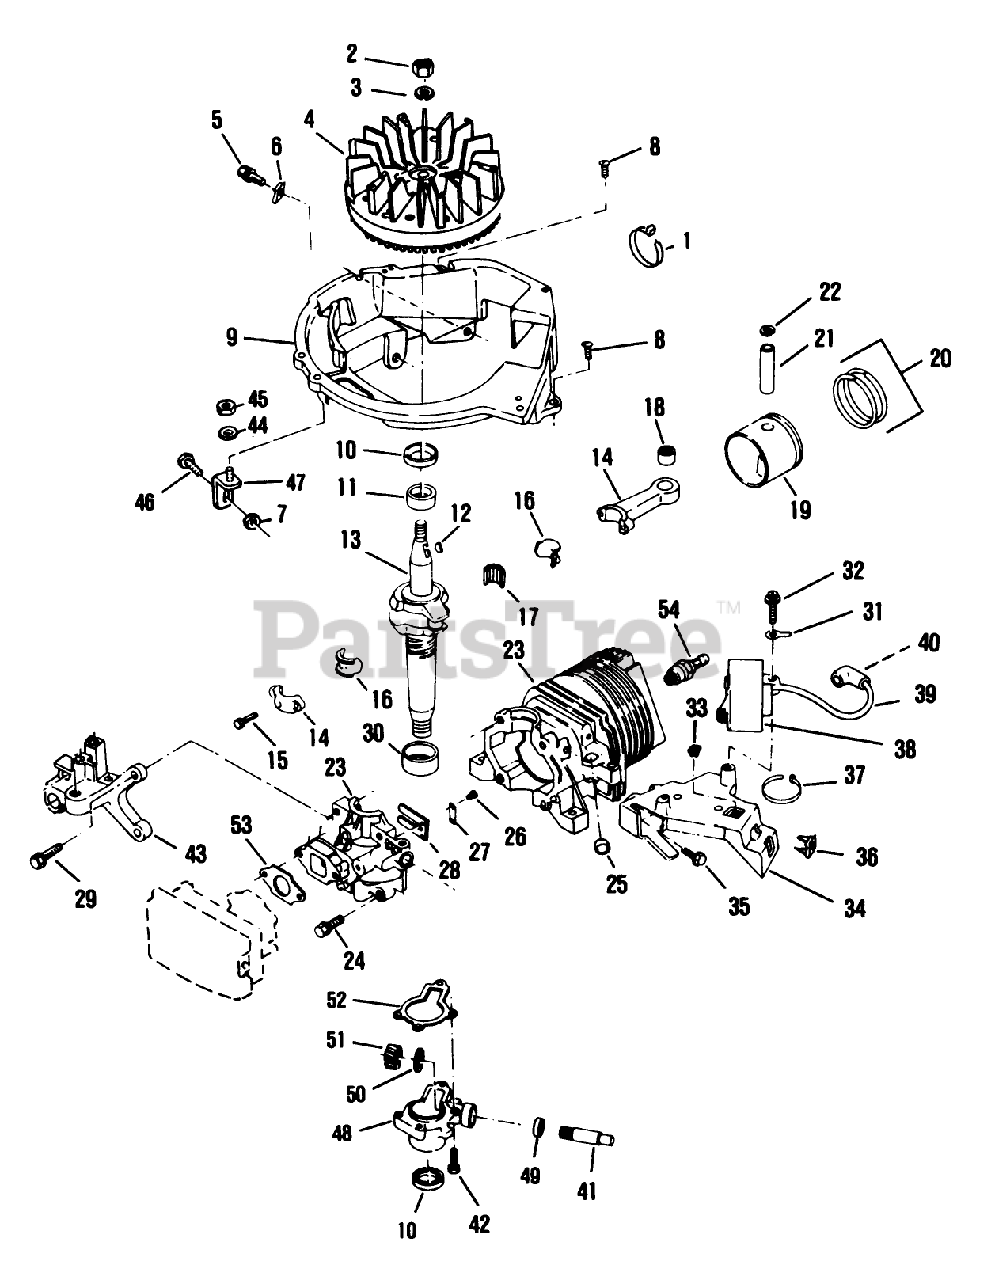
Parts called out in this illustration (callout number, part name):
2	NUT
4	FLYWHEEL ASSY F
5	SCREW-SEMS
7	NUT-LOCK F
8	SCREW F
10	SEAL-OIL
11	BEARING V
12	KEY
15	SCREW-HSH
16	LINER ASM
18	BEARING AY F
22	RING-RETAINING
24	SCREW S
25	PLUG-CORE VF
27	PLATE-BACKUP, REED
30	BEARING S
31	TERMINAL S
33	NUT-CLIP
34	BRACKET S
36	NUT-CLIP
39	HT LEAD&COVER XEV
43	BRACKET-BRAKE F
44	WASHER S
45	LOCKNUT E
46	BOLT F
47	BRACE AY F
49	SEAL S
50	THRUST WASHER
51	GEAR, DR SHAFT S
52	GASKET S
53	GASKET CARB S
